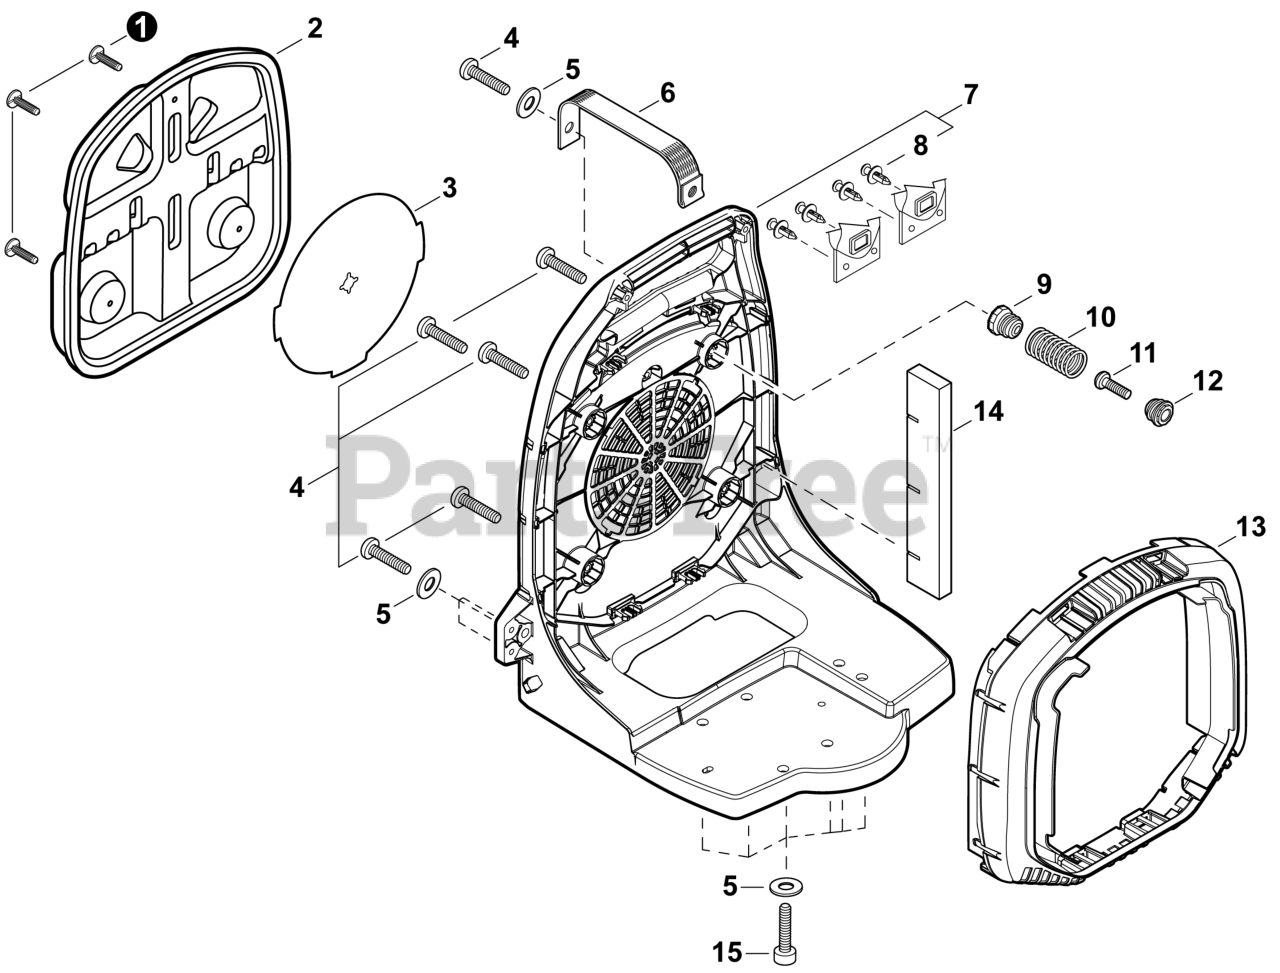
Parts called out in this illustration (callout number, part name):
2	CUSHION, BACKPACK
3	INSERT, COLD WEATHER
4	BOLT, TORX 5x20
5	WASHER 5.5x16x2T
6	STRAP, SAFETY 1.2x100
7	FRAME, BACKPACK WITH CLIPS
8	CLIP
9	HOLDER, SPRING
10	SPRING, COMPRESSION
11	BOLT, TORX 5x16
12	HOLDER, SPRING
13	GUARD, DEBRIS
14	PAD, FOAM
15	SCREW 5x25
